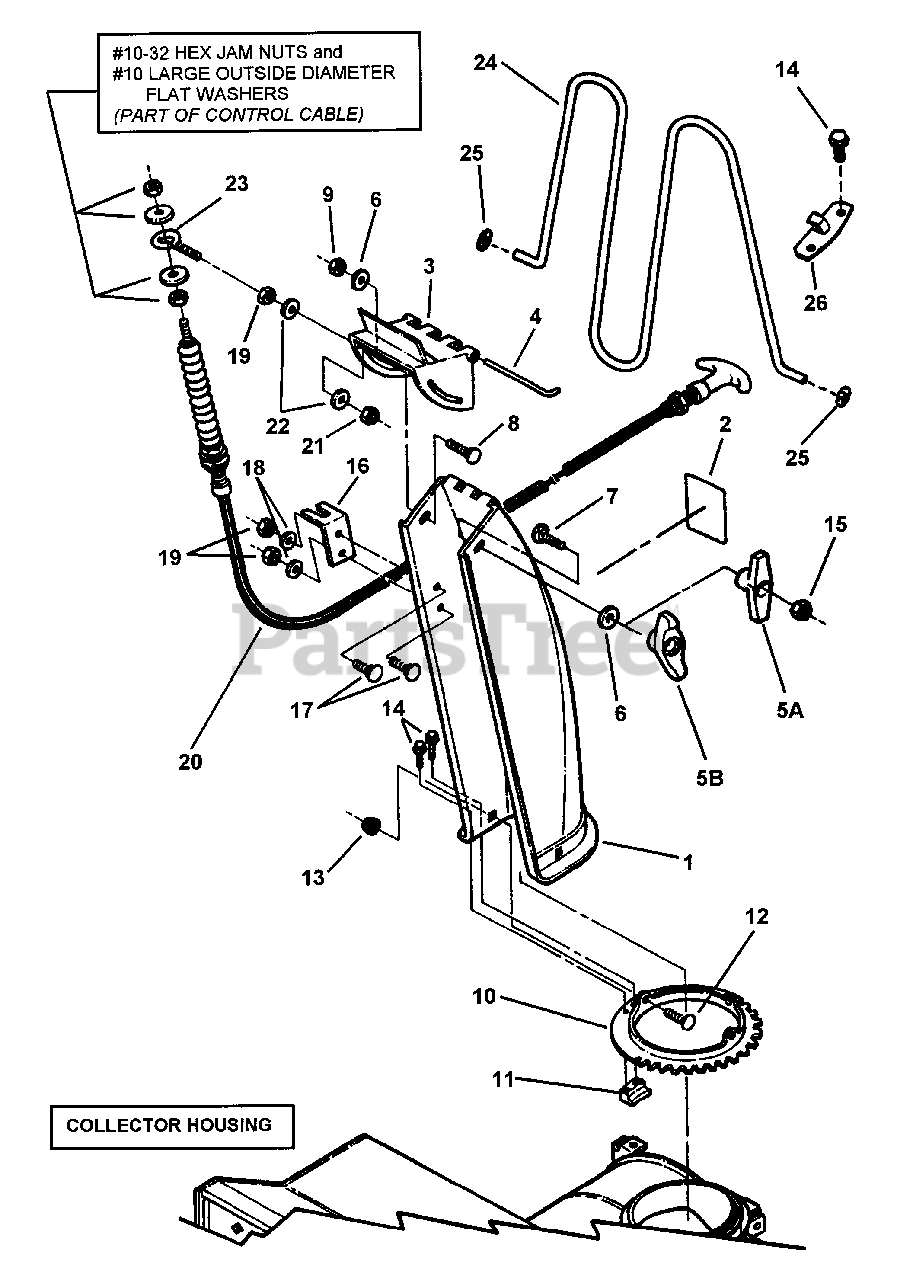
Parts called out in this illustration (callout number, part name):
1	CHUTE, Discharge
2	DECAL, Hand Danger
3	DEFLECTOR, Remote Control Discharge
4	PIN, Hinge
5A	T-KNOB (Plastic)
5B	T-KNOB (w/5/16-18 insert)
6	WASHER, 5/16 Flat
7	BOLT, 5/16-18 x 1" Square Neck Carriage, Grade 5
8	SCREW, 5/16-24 x 3/4" Hex Head Cap, Grade 5
9	NUT, 5/16-24 Hex Center Lock, Grade B
10	RING, Chute (59 Tooth, 229 Degrees)
11	RETAINER (Chute Ring to Housing)
12	BOLT, 5/16-18 x 5/8" Square Neck Carriage, Grade 5
13	NUT, 5/16-18 Hex Flange Lock, Grade 5
14	SCREW, #10-24 x 5/8" Hex Washer Self-Tap, Grade 5
15	NUT, 5/16-18 Hex, Grade B or 5
16	MOUNT, Cable
17	BOLT, 1/4-20 x 1/2" Short Neck Carriage, Grade 5
18	WASHER, 1/4" Internal Tooth Lock
19	NUT, 1/4-20 Hex
20	CABLE, Control
21	NUT, 1/4-20 Hex Center Lock, Grade B or 5
22	WASHER, 1/4 Flat
23	BOLT, 1/4-20 x 1-1/2" Eye
24	WIRE, Safety
25	PUSH-ON Fastener, 5/32" Dia.
26	RETAINER, Safety Wire
